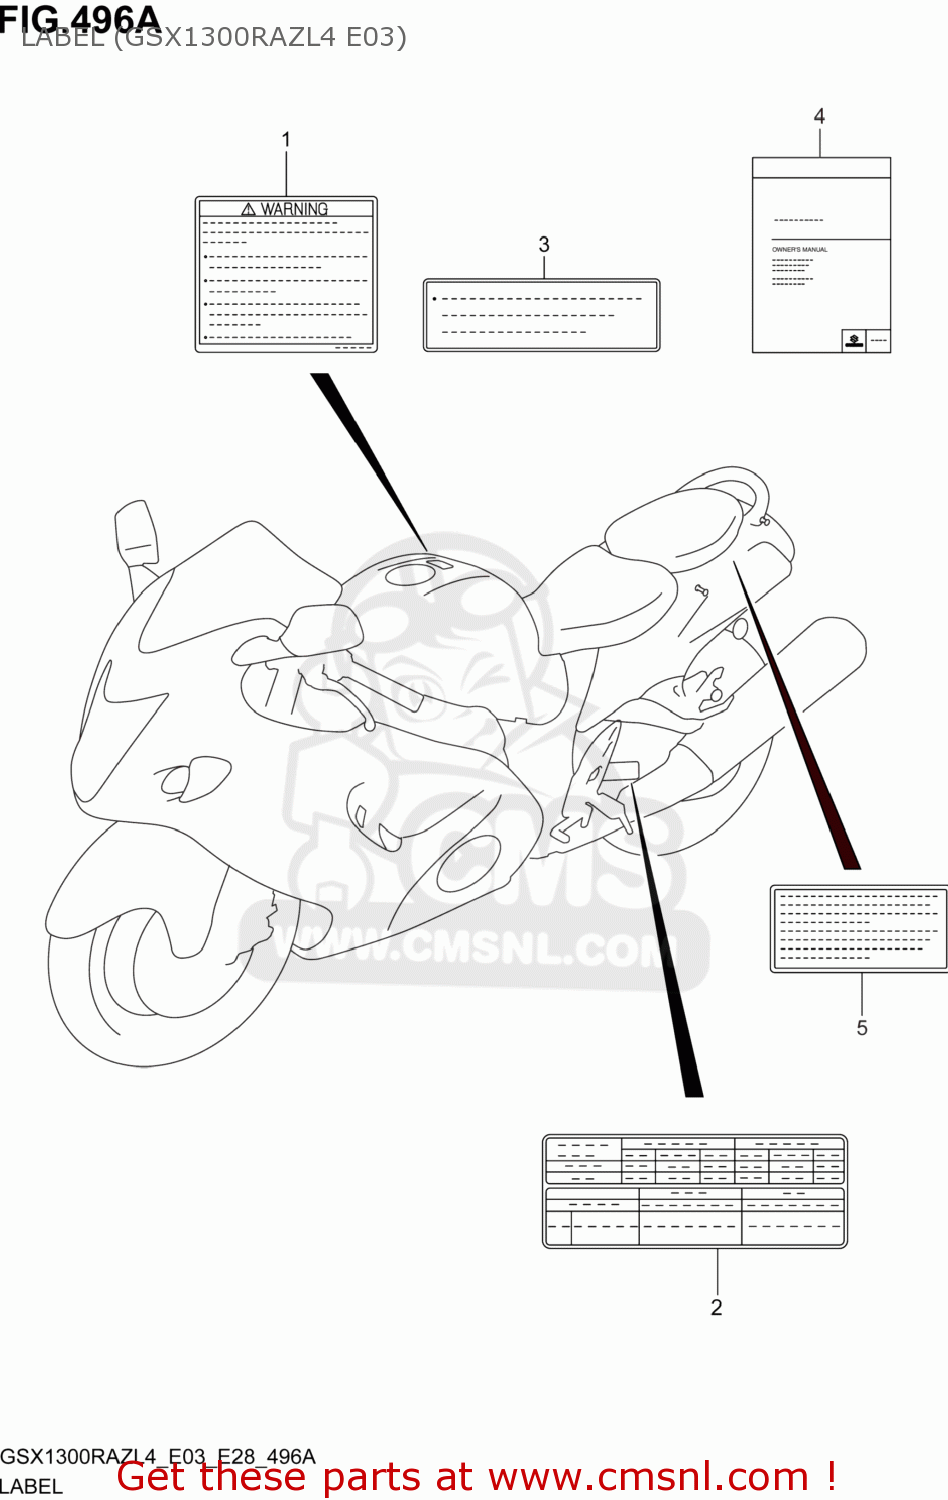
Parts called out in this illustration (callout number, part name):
1	LABEL,GENERAL WARNING
2	LABEL,TIRE INFORMATION
3	LABEL,FUEL INFORMATION
4	MANUAL,OWNER'S
5	LABEL,MANUAL NOTICE
